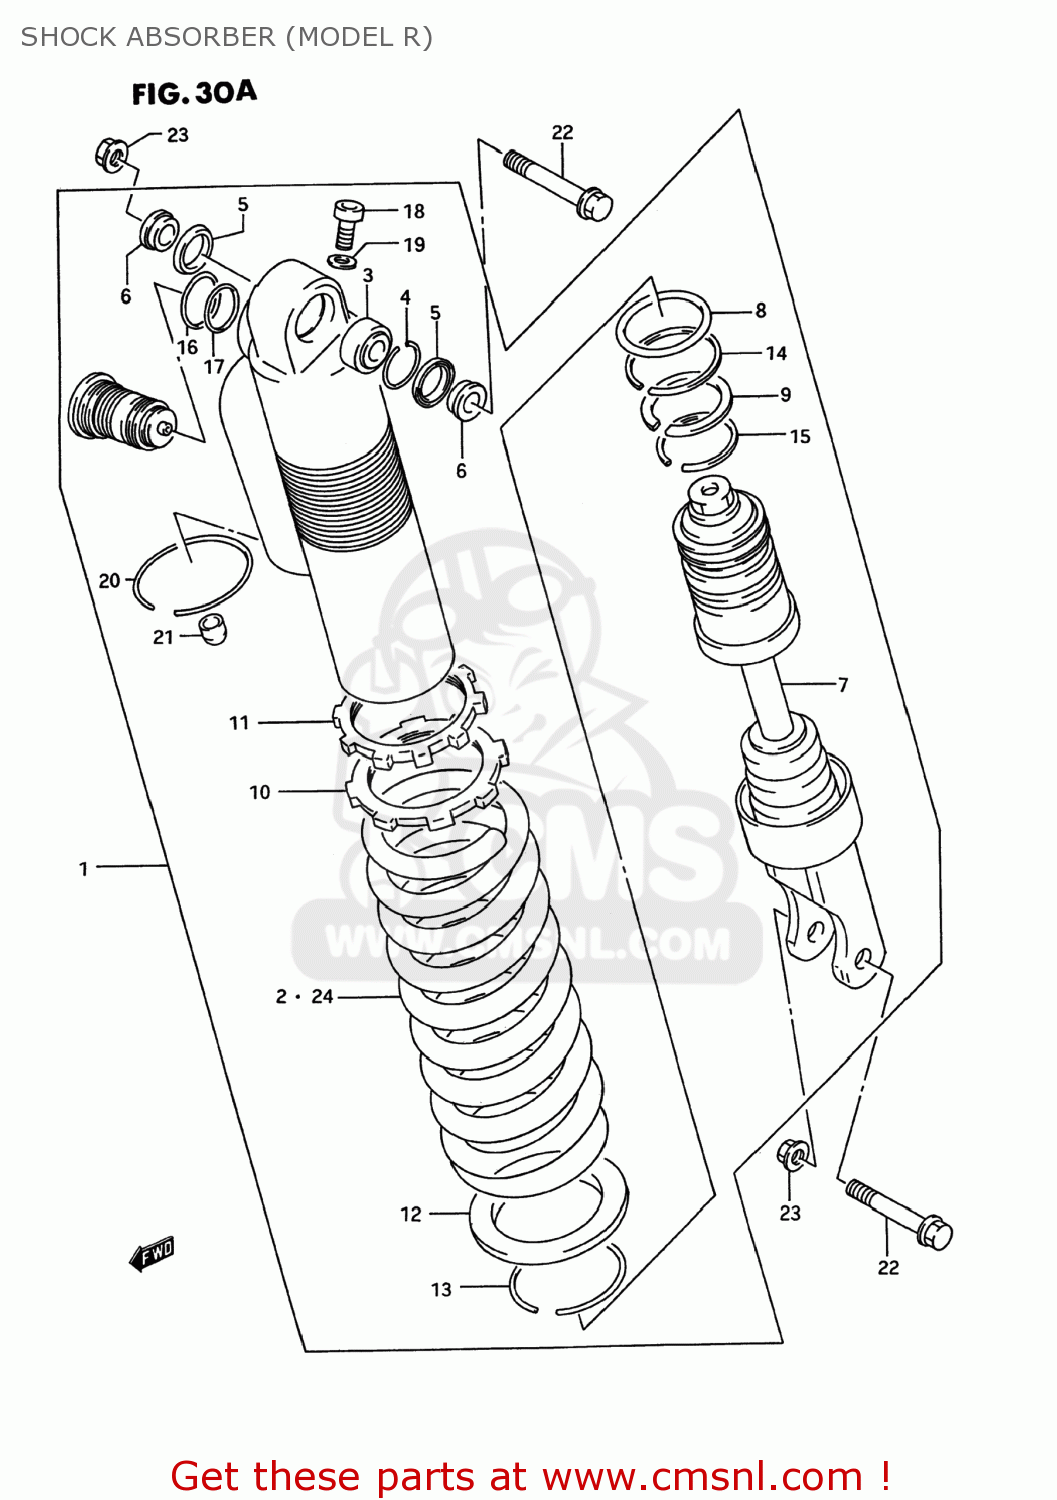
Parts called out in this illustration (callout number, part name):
1	ABSORBER ASSEMBLY,REAR SHOCK
2	SPRING,REAR (K=5.0)
3	BEARING,RR CUSHION LEVER RR
4	RING,STOPPER
5	SEAL,DUST
6	COLLAR
7	ROD,PISTON
8	O RING
9	STOPPER
10	GUIDE,SPRING
11	NUT
12	SEAT,SPRING
13	RING,STOPPER
14	RING,STOPPER
15	RING,STOPPER
16	O RING
17	O RING,CTR BOLT UPR
18	BOLT,REAR SHOCK ABSORBER
19	GASKET,DRAIN,PLUG (NAS)
20	RING,STOPPER
21	CAP
22	BOLT,RR SHOCK ABSORBER
23	NUT
24	SPRING
